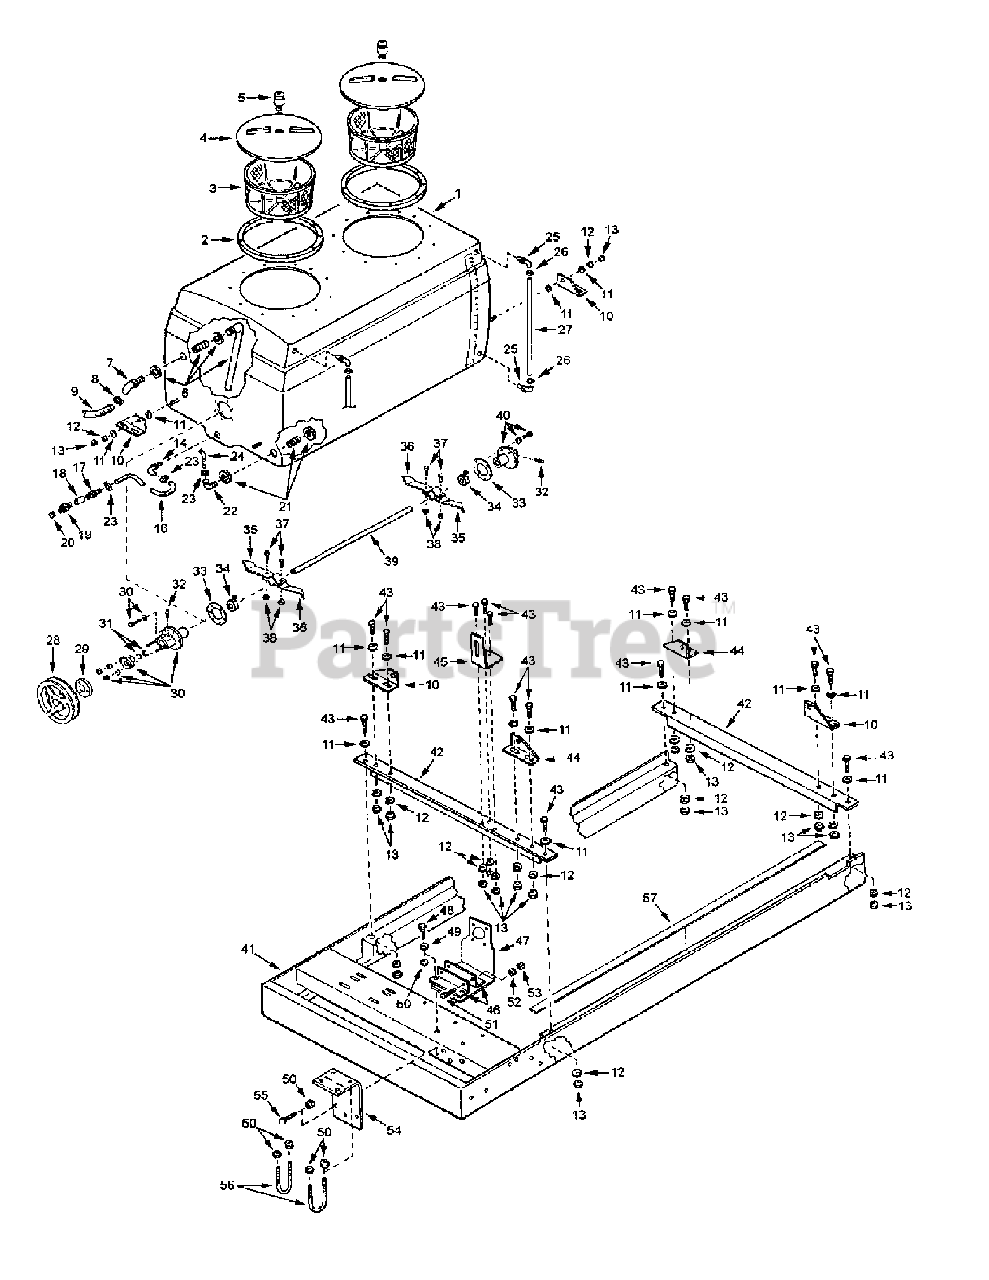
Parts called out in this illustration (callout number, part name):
1	300-Gallon Fiberglass Tank
2	Fillwell, 16, Threaded
3	Strainer Basket, 16"
4	Fillwell Cover, 16" Threaded
5	Vent for 16", Threaded
6	Suction Assembly
7	Elbow, 90°, 1-1/4 MPT x 1-1/4 Hose Barb
8	Hose Clamp, Wormgear, 1-1/4-1-1/2
9	Hose, 1-1/4" Spiraflex (Sold per foot)
10	Mounting Bracket, Tank
11	Flat Washer, 3/8
12	Lock Washer, 3/8
13	Hex Nut, 3/8-16
14	Elbow, 90°.
16	Hose, 3/4" Spiraflex (Sold per foot)
17	Hose Barb, 3/4 MPT x 3/4 Hose
18	Ball Valve 3/4"
19	Adapter, 3/4 MPT x 3/4 NH(M), Brass
20	Hose Cap, 3/4 NH(F), Brass
20	Hose Washer, 3/4 Package of 10
21	Return Assembly
22	Elbow, 90°, 1 MPT x 1/2 Hose Barb
23	O-Clamp, 7/8" for 1/2" Hose
24	Hose, 5/8" PVC (Sold per foot)
25	Elbow, 90°.
26	Hose Clamp
27	Sight Gauge
28	Sheave
29	Sheave Bushing
30	Stuffing Box
31	Packing
32	Grease Zerk
33	Gasket
34	Collar
35	Agitator Paddle, R.H.
36	Agitator Paddle, L.H.
37	Cap Screw
38	Hex Nut
39	Agitator Shaft
40	End Bearing Assembly
41	300 Gallon Frame, Fiberglass Sprayer
42	Crossmember
43	Cap Screw, 3/8-16 x 1 Hex Hd
44	Mounting Bracket, Tank
45	Idler Bracket
46	Pump Base, D-50 Pump
47	Pump Bracket
48	Cap Screw, 5/16-18 x 1 Hex Hd.
49	Flat Washer, 5/16
50	Hex Nut, 5/16-18 Nylock
51	Cap Screw, 7/16-14 x 2-1/2 Hex Hd.
52	Lock Washer, 7/16
53	Hex Nut, 7/16-14
54	Manifold Mount
55	Cap Screw, 5/16-18 x 3/4 Hex Hd.
56	U-Bolt 5/16-18 x 2 x 2-11/16
57	Foam, Adhesive Backed (Sold per foot)
